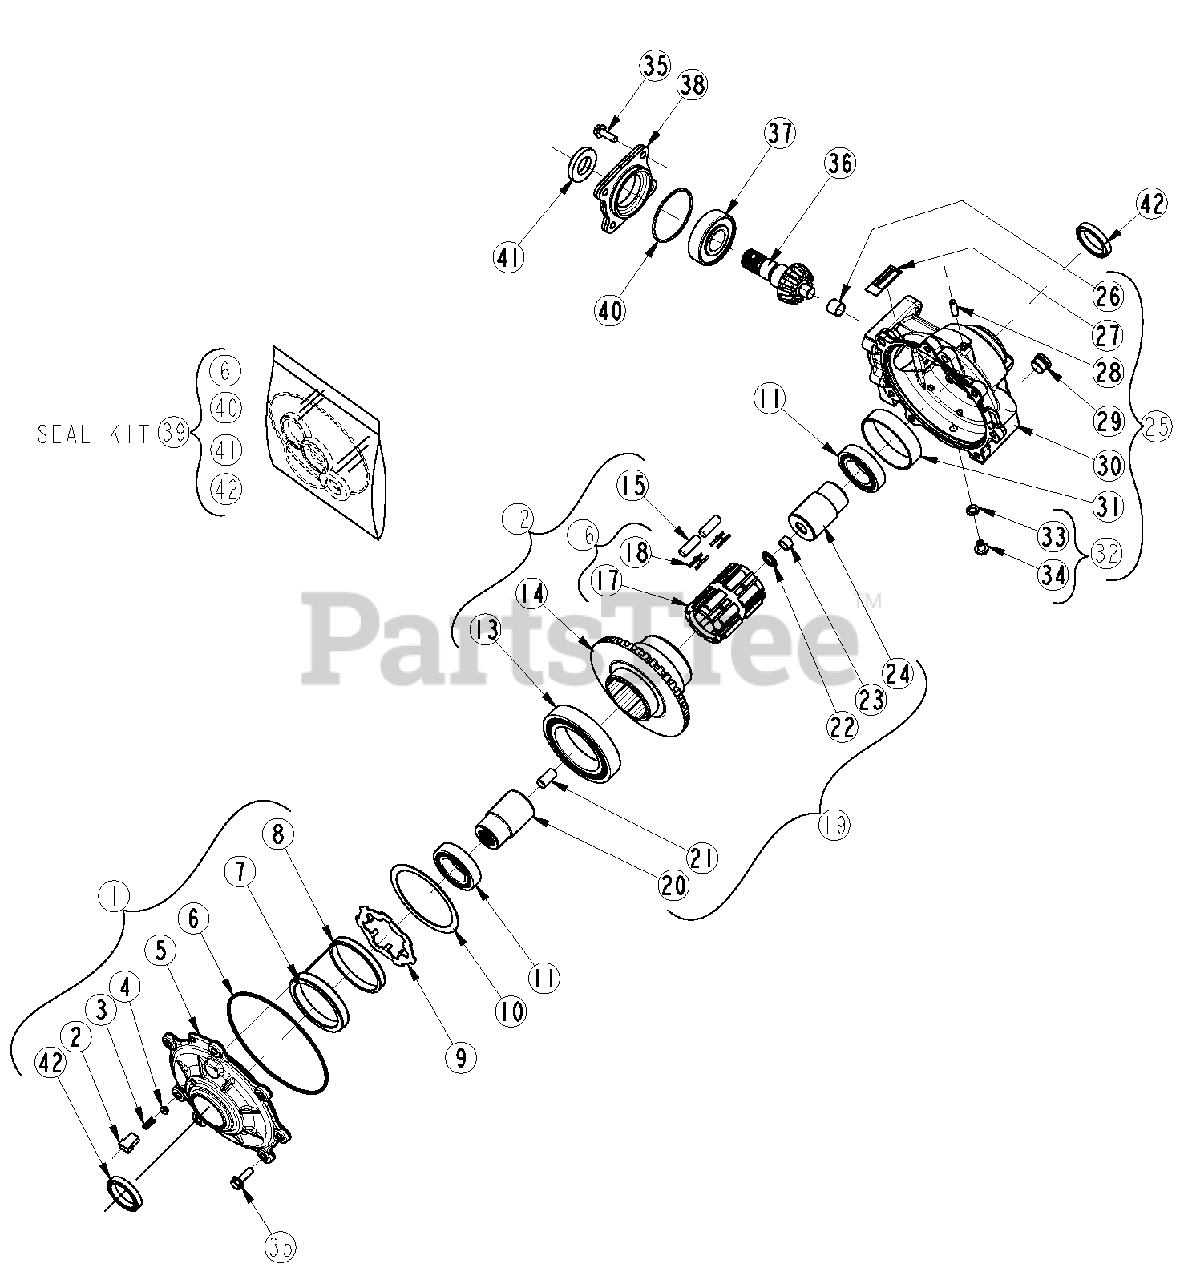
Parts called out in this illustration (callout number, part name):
1	OUTPUT COVER PLATE ASSEMBLY #1 Kit (Includes #2 to #8 & 42)
9	ARMATURE PLATE
10	SHIM .05 THICK BRASS, HALF HARD
11	6008-C3 DEEP GROOVE ROLLER BEARING
12	CLUTCH ASSEMBLY #12 Kit (Includes #13 to #16)
13	6015-C3 DEEP GROVE ROLLER BALL BEARING (Sold separately & with #12 Kit)
14	CLTH.HSG./RNG GR., 42T 6.75DP (with #12 Kit) Not serviced, replaced by 6203-9U-088, item 43
15	ROLL KIT (Sold separately & with #12 Kit)
16	ROLL CAGE ASSEMBLY #16 Kit (Includes #17 & #18)
18	SPRING KIT, H-CLIP .008 THK (Sold separately & with #16 Kit)
19	RACE/OUTPUT HUB ASSEMBLY #19 Kit (Includes #20 to #21)
21	PERMIGLIDE BUSHING (Sold with #19 Kit)
22	TC815 NEEDLE ROLLER THRUST BEARING (Sold separately & with #19 Kit)
23	1/2 DIA X 1 LG. DOWEL PIN (Sold separately & with #19 Kit)
25	GEARCASE ASSEMBLY #25 Kit (Includes #26 to #32)
26	DU BUSHING (Sold with #25 Kit)
29	PLUG OIL FILL 3/4-16 HOLLOW HEAD (Sold separately & with #25 Kit) Torque item #29 (PLUG OIL FILL 3/4-16 HOLLOW HD) Tighten to 10
32	DRAIN PLUG ASSEMBLY #32 Kit (Includes #33 & #34)
35	BOLT KIT Torque item #35 (5/16" X 1" Hex Head Bolts) Tighten to17 ft-bs
36	SHAFT PNION 11T3.75DP, MACHINED, Not serviced, replaced by 6203-9U-088
37	6306-03-C3 DP GROOVE ROLLER BALL BEARING
38	COVER PLATE, INPUT-MACHINED
39	MINOR REPAIR KIT #39 Kit (Includes #6 & #40 to #42)
41	TRIPLE LIP OIL SEAL (Sold with #1 Kit & #39 Kit)
42	OIL SEAL, OUTPUT (Sold with #39 Kit)
43	KIT-GEAR, HARD TURNED (Includes #14 & #36)
